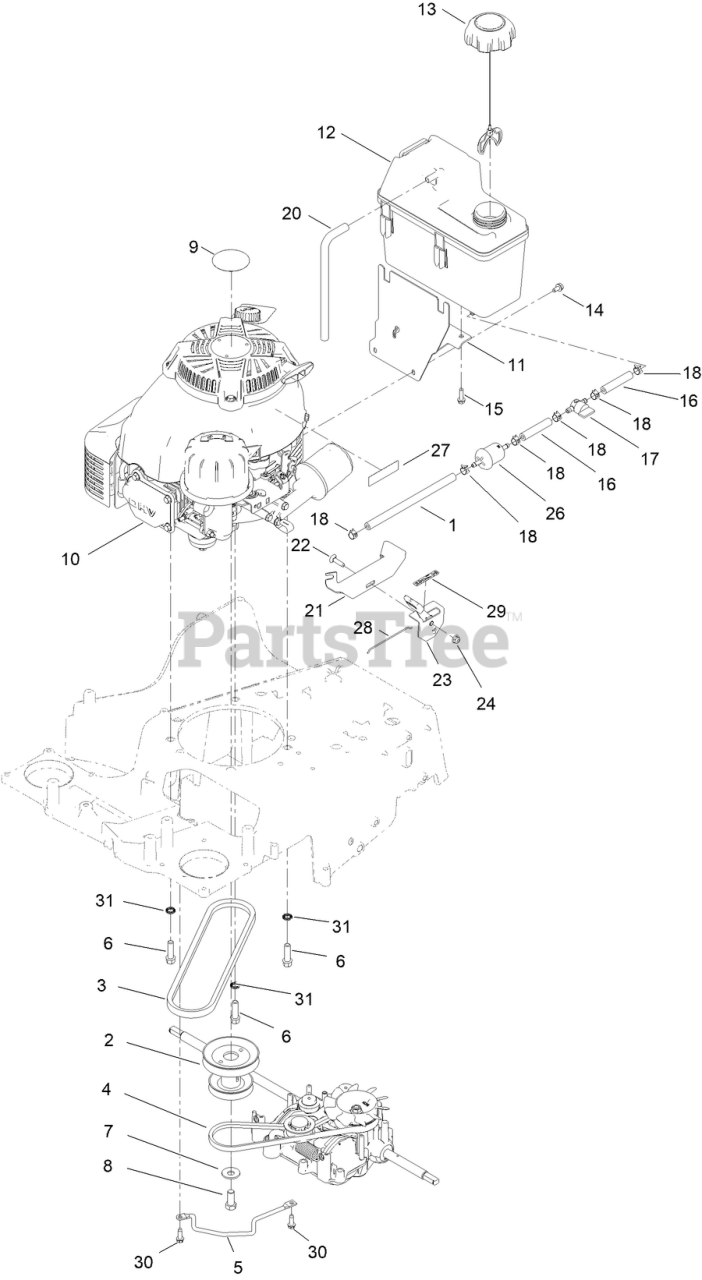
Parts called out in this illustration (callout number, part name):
1	HOSE-FUEL
2	PULLEY-ENGINE
3	V-BELT
4	BELT-V
5	ROD-GUIDE, BELT
6	SCREW-TAPTITE
7	WASHER-BELLEVILLE
8	SCREW-HH
11	MOUNT-TANK
12	TANK-FUEL
13	CAP-FUEL
14	SCREW-HWH
15	SCREW-HWH
16	HOSE-FUEL
17	VALVE-FUEL
18	CLAMP-HOSE
20	HOSE-VENT, CANISTER
21	BRACKET-MOUNT, THROTTLE
22	SCREW-CARR
23	CONTROL-THROTTLE
24	NUT-HF
26	FILTER-FUEL
27	DECAL-WARNING, ENGINE
28	WIRE-CONTROL
29	DECAL-THROTTLE, CHOKE
30	SCREW-HWHTF
31	WASHER-LOCK
